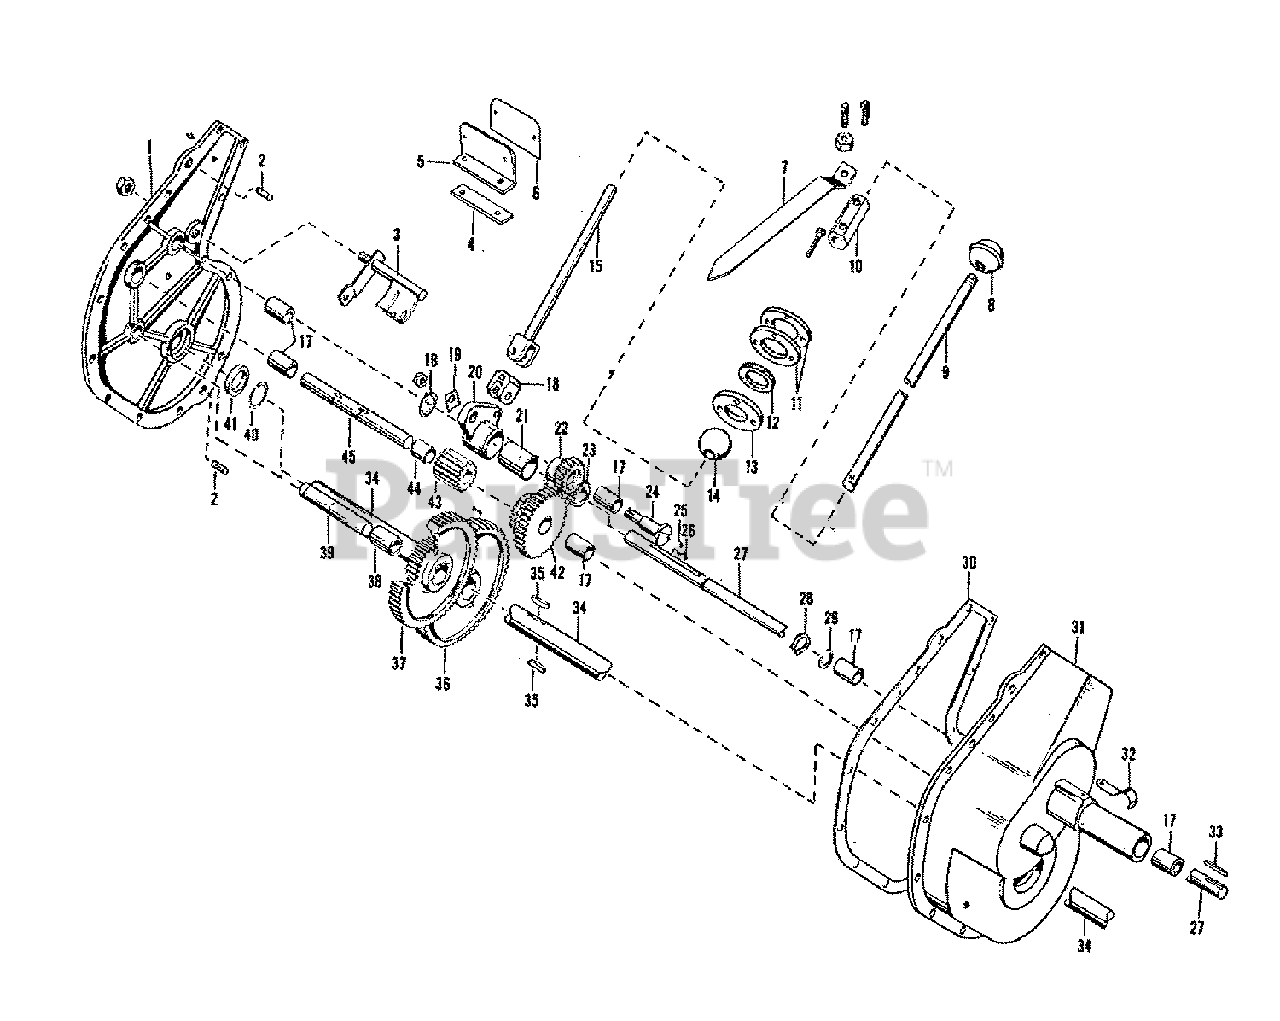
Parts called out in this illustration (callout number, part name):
1	COVER, Gear Case
2	PIN, Dowel
3	SHIFT GUIDE ASSEMBLY
4	SHIFT INST. PLATE BRACKET HOLDER
5	SHIFT INST. PLATE BRACKET
6	PLATE, Serial and Shift Instr.
7	POINTER, Shifter
8	BALL, Shift Lever
9	HANDLE EXT. Gear Shift
10	HANDLE COUPLING, Gear Shift
11	SPACER, Shift Ball
12	WASHER, Shift Ball
13	RETAINER, Gear Shift Ball
14	GEAR SHIFT BALL
15	PITMAN CLEVIS ASSEMBLY
16	GEAR SHIFT PITMAN
17	BRONZE BEARING
18	RING, Retaining
19	PLATE, Lock
20	ROCKER ARM ASSEMBLY
21	BEARING, Rocker Arm
22	PINION WITH BEARING, Rocker Arm
23	TRANSMISSION SLIDE GEAR
24	PIN, Rocker Arm Pinion
25	LOCK PLATE, Slide Key
26	SLIDE KEY, Transmission
27	SHAFT, Transmission Pulley
28	RING, Retaining
29	WASHER, Spacer
30	GASKET, Gear Case
31	GEAR CASE
32	LATCH, Idler Lever
33	PULLEY KEY, Transmission
35	KEY, Axle
36	GEAR, Drive
37	CLUSTER GEAR ASSEMBLY
38	BUSHING, Intermediate, 5/8 x 3/4 x -1-7/16"
39	SPINDLE, Intermediate
40	RING, Retaining
41	WASHER, Retaining
42	CLUSTER GEAR ASSEMBLY
43	HIGH GEAR
44	SPACER, Transmission Pinion Shaft
45	SHAFT, Transmission Pinion
